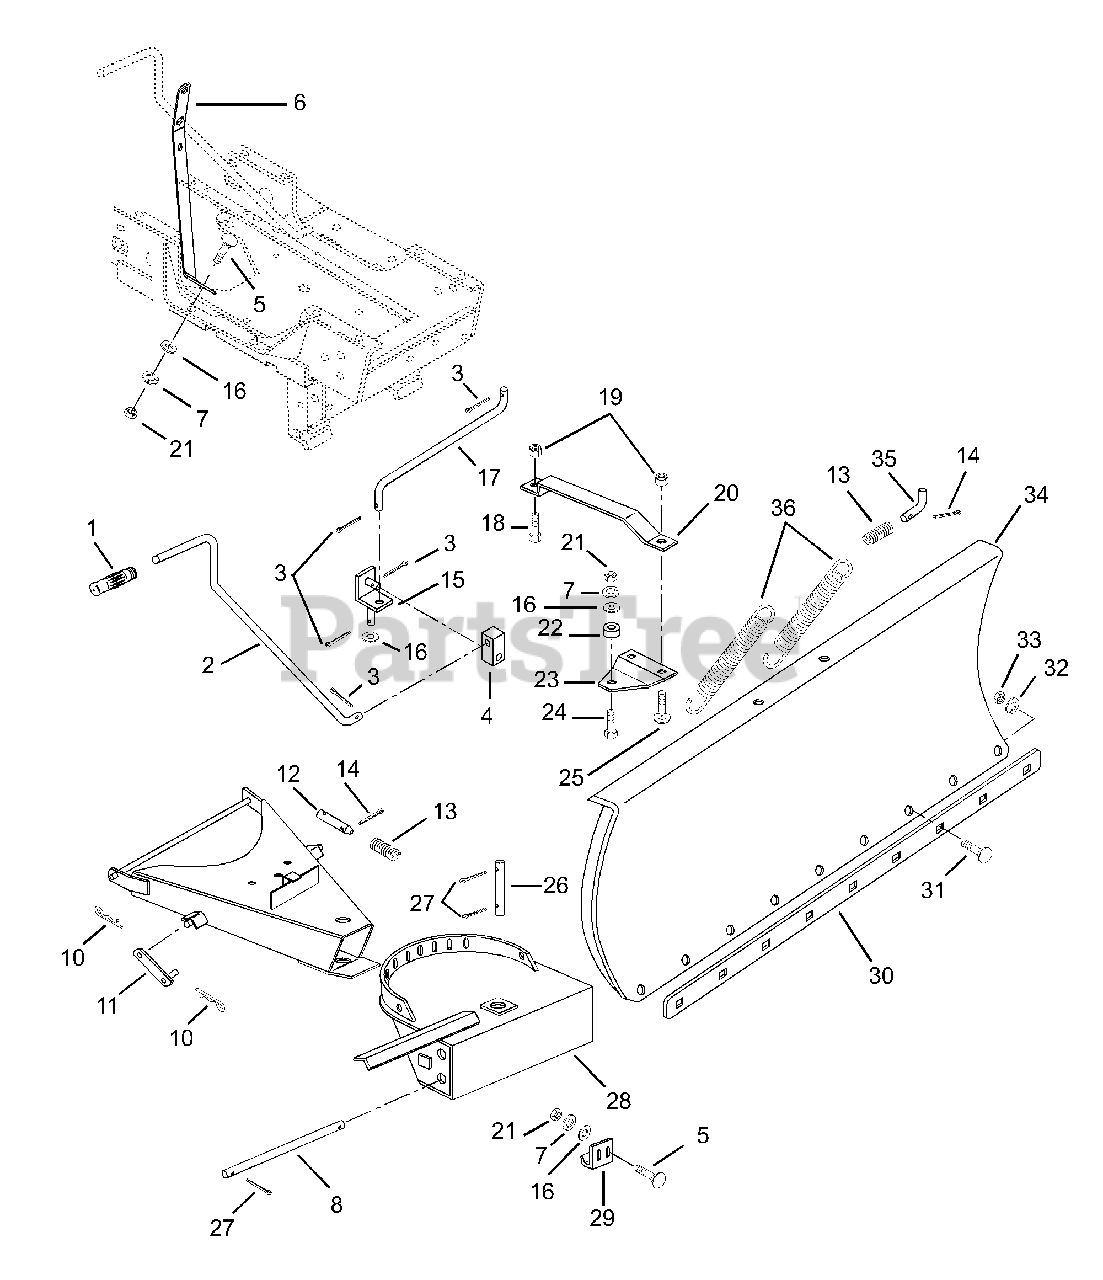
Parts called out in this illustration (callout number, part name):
1	Grip
2	Rod
3	Pin-Cotter .12 x .75
4	Universal Block Joint
5	Bolt-Round Head Square Neck .38-16 x 1.0
6	Support Rod
7	Washer-Lock .375 x .094
8	Rod
9	54 In Frame
10	Pin-Hair Internal .14 x .43 x 2.75
11	Arm-Lift Link
12	Latch Pin
13	Spring-Compression .080 x .85 x 1.44
14	Pin-Cotter .12 x 1.0
16	Washer-Flat-Steel .438 x 1.00 x .083
17	Rod
18	Bolt-Hex .31-18 x 1.25 Grade 2
19	Nut-Locking .312-18
20	Strap
21	Nut-Hex .375-16 Grade 2
23	Pivot Plate
24	Bolt-Hex .38-16 x 1.00
25	Bolt-Round Head Square Neck .31-18 x .75
26	Pin
27	Pin-Cotter .18 x 1.0
28	Pivot-Plate
29	Skid Shoe
30	Wear Plate
31	Bolt-Round Head Square Neck .312-18 x 1.00
32	Washer-Lock .312 x .097
33	Nut-Hex .312-18 Grade 2
34	54 In Blade
35	Jack Pin
36	Spring-Tens .187 x .50 x 9.94
